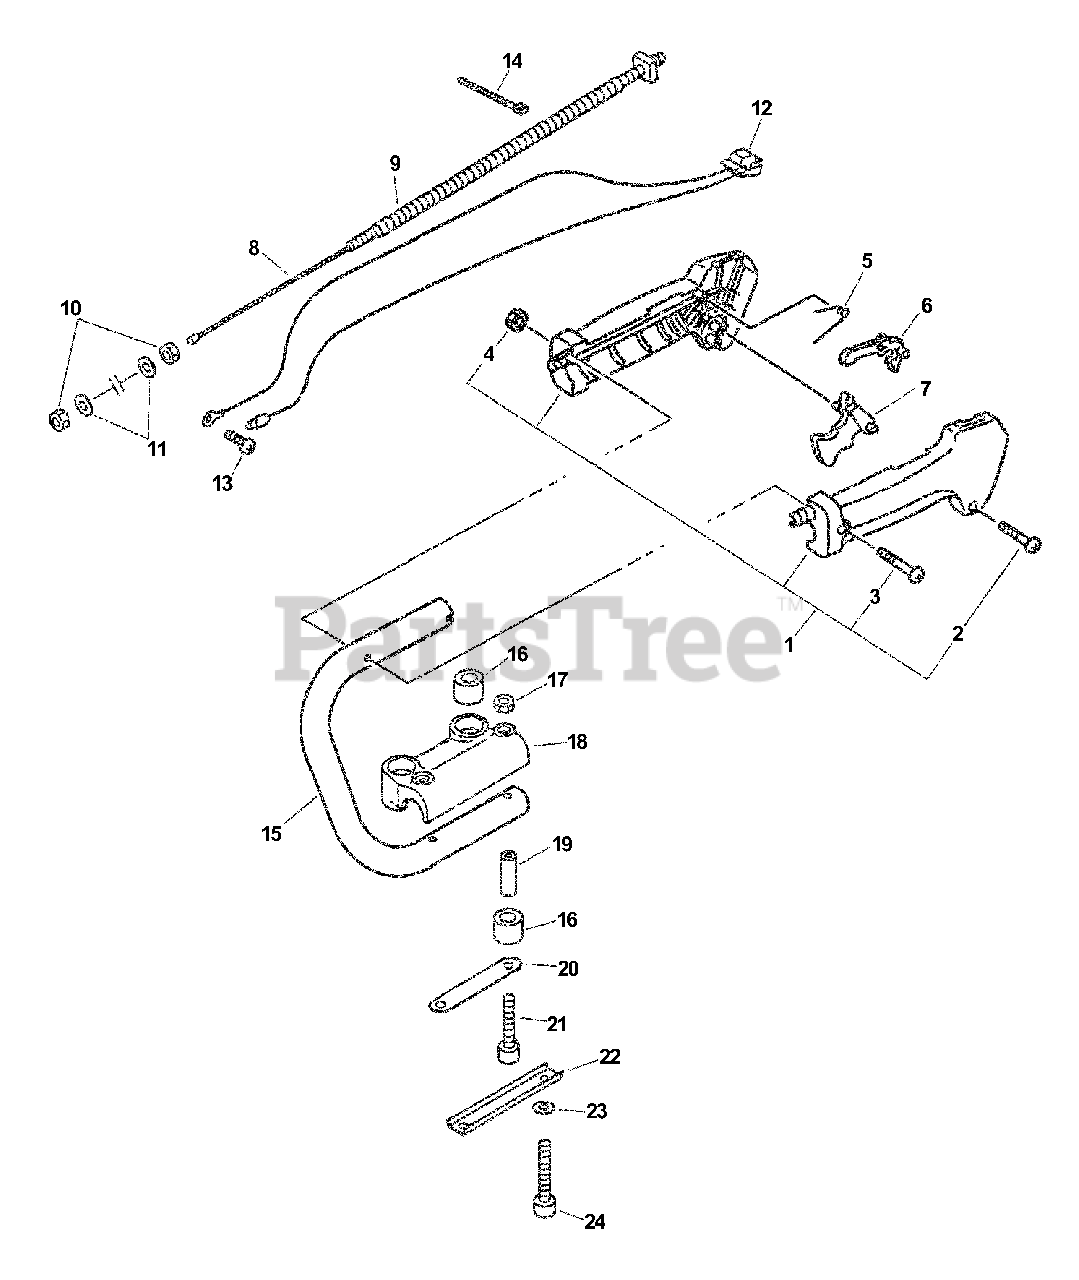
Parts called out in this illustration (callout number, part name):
1	THROTTLE CONTROL ASSY
2	SCREW - 3X25
3	SCREW - 5X30
5	SPRING, LOCKOUT LEVER
6	LOCKOUT, THROTTLE
7	TRIGGER, THROTTLE
8	CABLE, THROTTLE
11	WASHER - 6
12	IGNITION SWITCH ASSY
13	SCREW - 5X10
14	TIE, CABLE
15	HANDLE - REAR
18	SUPPORTER, HANDLE
19	SPACER
20	PLATE
21	SCREW - 5X40
22	BRACKET, HANDLE - LOWER
24	SCREW - 5X35
